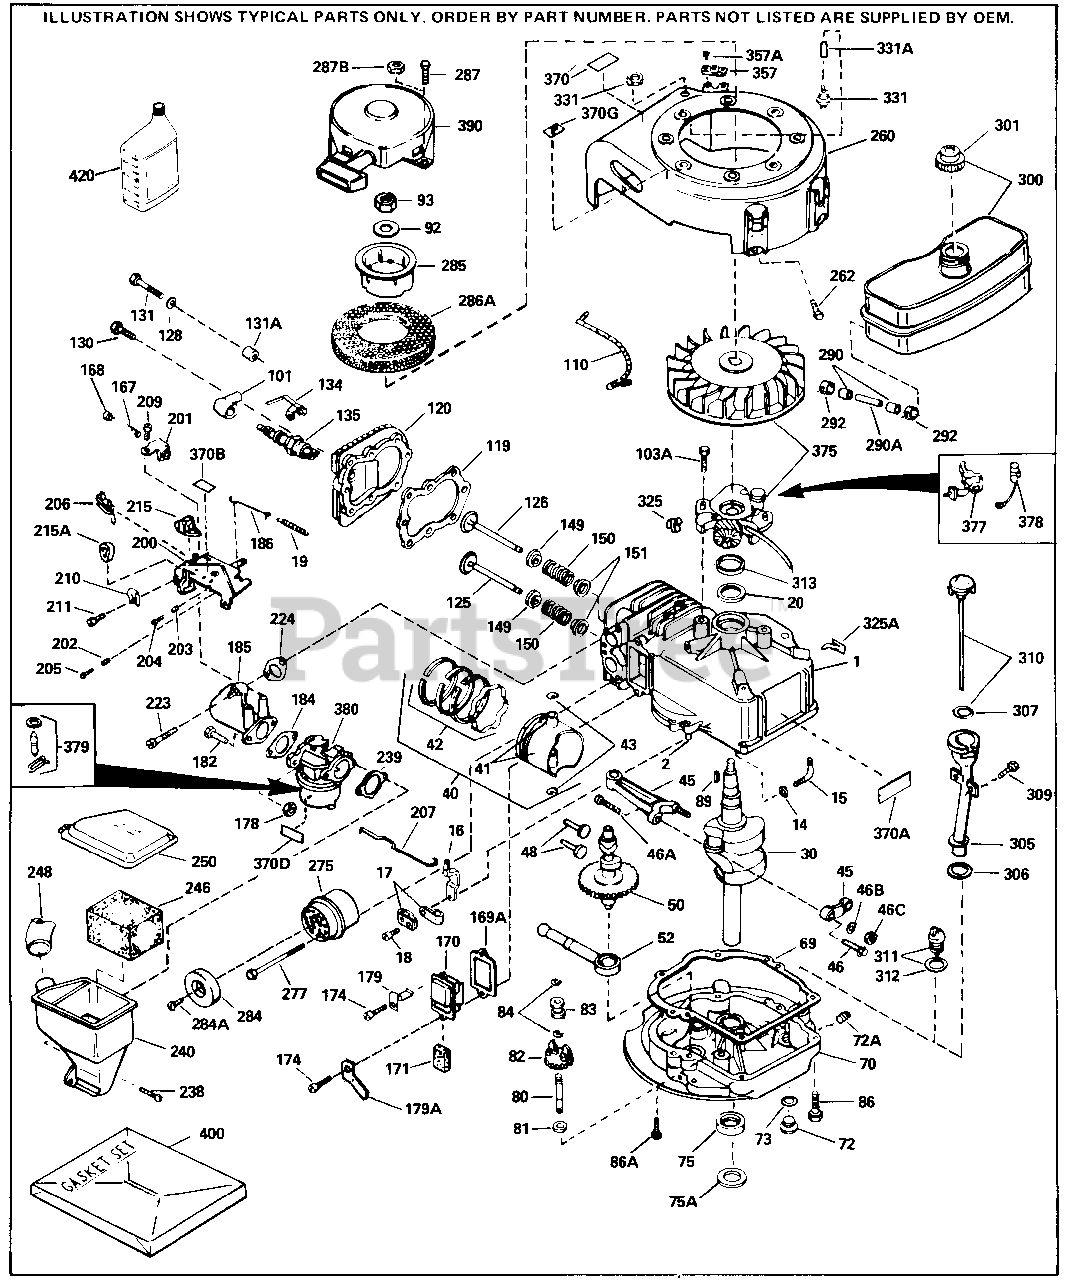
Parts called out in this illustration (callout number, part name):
1	"Cylinder (Incl. 2 & 20) 2-5/16" Bore
2	Dowel Pin
14	Flat Washer
15	Governor Rod (Incl. 14)
16	Governor Lever
17	Governor Lever Clamp Clamp is positio ned towardsspark plug end on 1977-78 and latermodels. It is positioned opp osite spark plugend on earlier models .
18	Screw, 8-32 x 5/16"
19	Spring, Governor
20	Oil Seal
30	Crankshaft
40	Piston, Pin & Ring Ass'y. (Std.) 2-5 /16"
40	Piston, Pin & Ring Ass'y. (.010" OS)
40	Piston, Pin & Ring Ass'y. (.020" OS)
41	Piston & Pin Ass'y. (Std.)(Incl. 43) 2-5/16"
41	Piston & Pin Ass'y. (.010" OS) Incl. 43
41	Piston & Pin Ass'y. (.020" OS) Incl. 43
42	Ring Set (Std.) (2-5/16" Bore)
42	Ring Set (.010" OS)
42	Ring Set (.020" OS)
43	Piston Pin Retaining Ring
45	Rod Assy., Connecting (Incl. No. 46)
46	Bolt, Connecting rod
46A	Connecting Rod Bolt Used on early pro duction
46B	Washer (Used on early production)
46C	Nut (Used on early production)
48	Valve Lifter
50	Camshaft
52	Oil Pump Ass'y.
69	* Gasket, Mounting flange
70	Flange Ass'y. Incl. 72, 75, 80 & 311
72	Plug, Oil drain (Incl. No. 73)
73	* Oil Plug Gasket Do not use w/plastic plug
75	Oil Seal
80	Shaft, Governor
81	Washer, Flat
82	Gear Assy., Governor (Incl. No. 81)
83	Spool, Governor
84	Retaining Ring
86	Screw, 1/4-20 x 1-1/4"
89	Flywheel Key (also available in Packa ged Part #740007B)
92	Washer Belleville
93	Nut, Flywheel
103A	Screw, 1/4-20 x 5/8"
119	* Gasket, Cylinder head
120	Head, Cylinder (Incl. 131)
125	Exhaust Valve (Std.) (Incl. 151)
125	Exhaust Valve (1/32" OS) (Incl. 151)
126	Intake Valve (Std.) (Incl. 151)
126	Exhaust Valve (1/32" OS) (Incl. 151)
128	Washer n)
130	Screw, 5/16-18 x 1-1/2" (Use as requi red)(Do not usewith 26073)
131	Screw, 5/16-18 x 2" (Use as required)
131	Screw, 5/16-18 x 2-1/2" Use as requir ed
135	Resistor Spark Plug (RJ-8C)
149	Valve Spring Cap Used on early produc tion
150	Spring, Valve
151	Cap, Lower valve spring
169A	* Gasket, Breather
170	Breather Assy. (Incl. 169A & 171)
171	Element, Breather
174	Screw, 10-24 x 1/2"
178	Nut & Lock Washer 1/4-28
182	Screw, 1/4-28 x 7/8"
184	* Gasket, Carburetor
185	Pipe, Intake
186	Link, Governor spring
203	Spring, Compression
207	Link, Throttle
223	Screw, 1/4-20 x 1"
224	* Gasket, Intake pipe
238	Screw, 10-32 x 5/8"
239	* Gasket, Air cleaner
240	Body, Air cleaner
246	Air Filter
248	Tube, Air Cleaner
250	Cover, Air cleaner
260	Housing, Blower NOTE: Replacement har dware may differ when servicing start er assy. or blower housing. Refer to Service Bulletin 508.
275	Muffler Kit (Incl. Nos. 274 & 277)
277	Screw, 1/4-20 x 2-1/4"
285	Cup, Starter
286A	Screen, Starter cup
287	Screw, 1/4-28 x 7/16"
290	Fuel Line (8.62") as req.)
290	Fuel Line (Braided 16")(40cm) Use as req.
292	Fuel Line Clamp
300	Fuel Tank Ass'y. (Incl. 292 & 301)
301	Fuel Cap (Red 1-1/2" ID) (also availa ble in Packaged Part #740005B) )
301	Fuel Cap (Use as required)
306	"O" Ring This "O" ring is required wi th metal fill tube only when replacem ent mounting flange with .777 dia. oi l fill hole has been used.
311	Oil Fill Plug (Incl. 312) also availa ble in Packaged Part #740079
312	* Gasket, Oil fill plug
313	Gasket, Stator
325	Wire Clip
375	Magneto NOTE: The complete magneto is not available as an assembly. The ma gneto number is shown for reference p urposes only. Order component parts i ndividually, as shown in parts list. (Refer to Division 5, Sec. B, page 35 or Fiche 7A, Grid G-1 fo
377	Breaker Points (also available in Pac kaged Part #740037B)
378	Condenser (also available in Packaged Part #740037B)
379	Inlet Needle, Seat & Clip Assy.
380	Carburetor (Incl. 184) (Refer to Divi sion 5, Section A, page A2-10 or Fich e 7A, Grid E-13 for breakdown)
390	Rewind Starter NOTE: Hardware may dif fer when servicing blower housing or starter assy. Refer to Service Bullet in 508. (Refer to Division 5, Section C, page 25 or Fiche 7A, Grid G-4 for breakdown)
400	* Gasket Set (Incl. items marked *)
420	SAE 30 4-Cycle Engine Oil (Quart)
